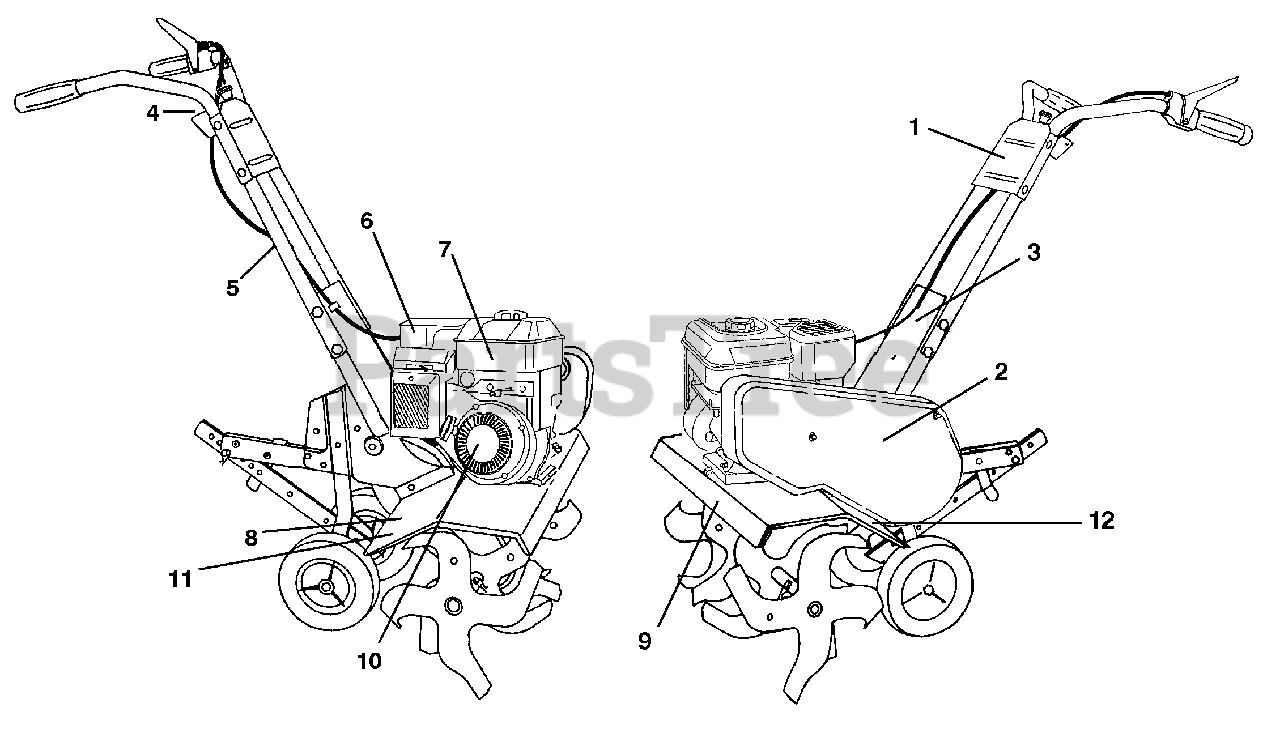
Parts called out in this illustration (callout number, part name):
1	Decal, Poulan Pro
2	Decal, Poulan Pro, 800 Series/26"
3	Decal, Forward and Reverse
4	Decal, Reverse, Tine Control
5	Decal, Hand Placement
6	Decal, Engine
7	Decal, OHV, I/C
8	Decal, Warning
9	Decal, Heavy Duty
10	Decal, Rewind Starter
11	Decal, Warning, Rotating Tines
12	Decal, Compliance
12	Manual, Operator's, English/French
12	Manual, Repair Parts
